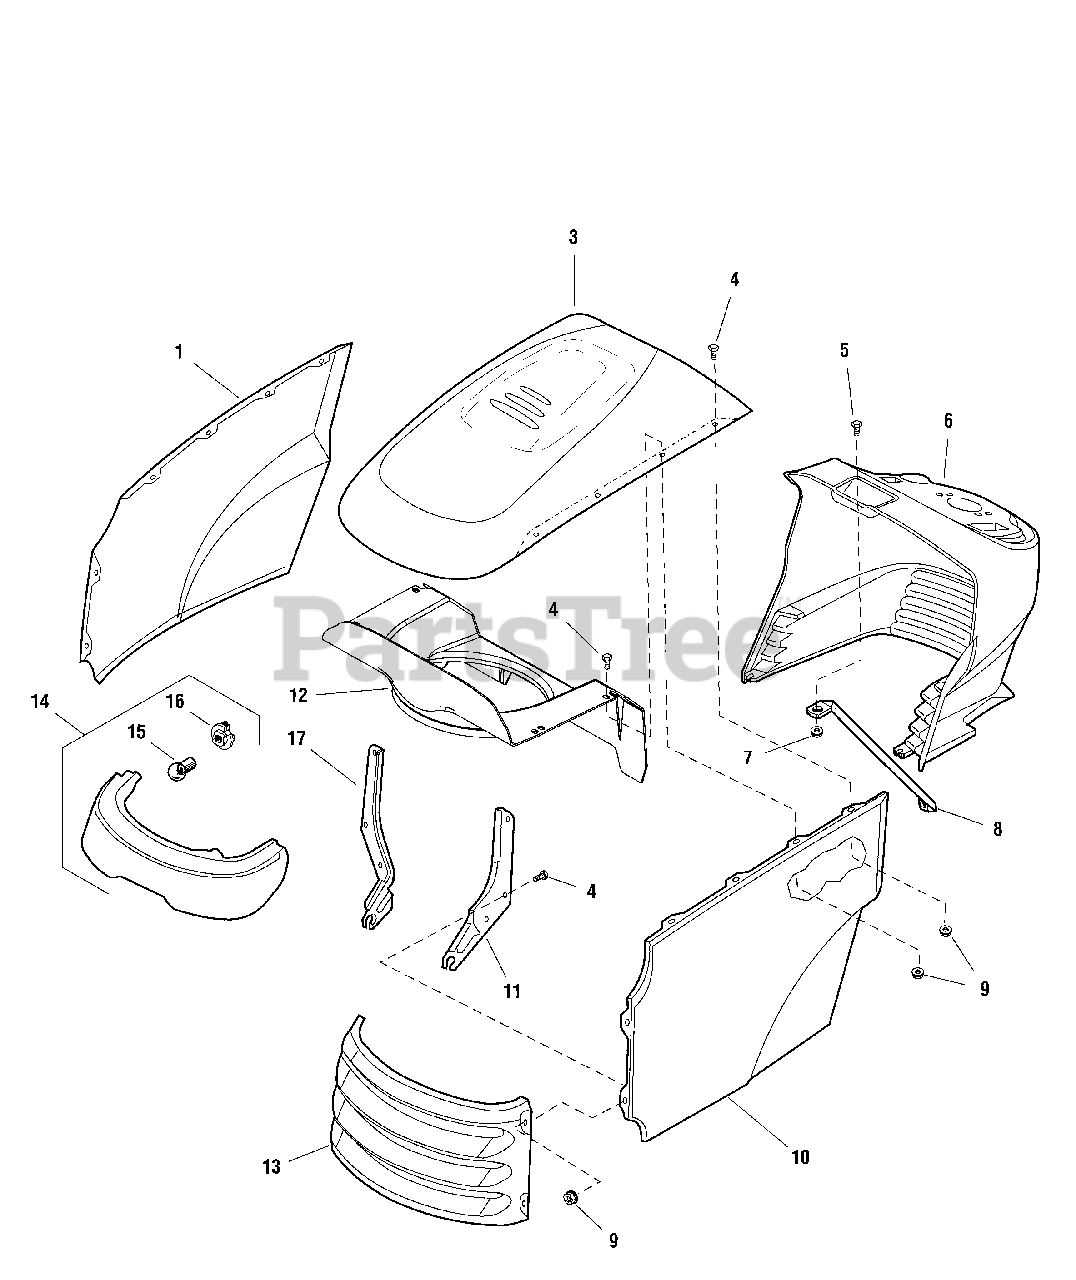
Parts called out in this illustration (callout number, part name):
1	PANEL, RH Side, Orange
3	HOOD, with Louvers, Orange
4	CAPSCREW, Hex Head Flange Lock,1/4-20 x 5/8
5	SCREW, Phillips Head, #10-24 x 1/2
6	DASHBOARD, RMO, Black
7	NUT, Hex Nylock,#10-24
8	ROD, Dash Support
9	NUT, Hex Flange Lock, 1/4-20
10	PANEL, LH Side, Orange
11	HINGE, LH
12	DUCT, Air Inlet, Plastic
13	GRILLE, Orange
14	HEADLIGHT ASSEMBLY
15	BULB, Headlight
16	SOCKET, Headlight
17	HINGE, RH
